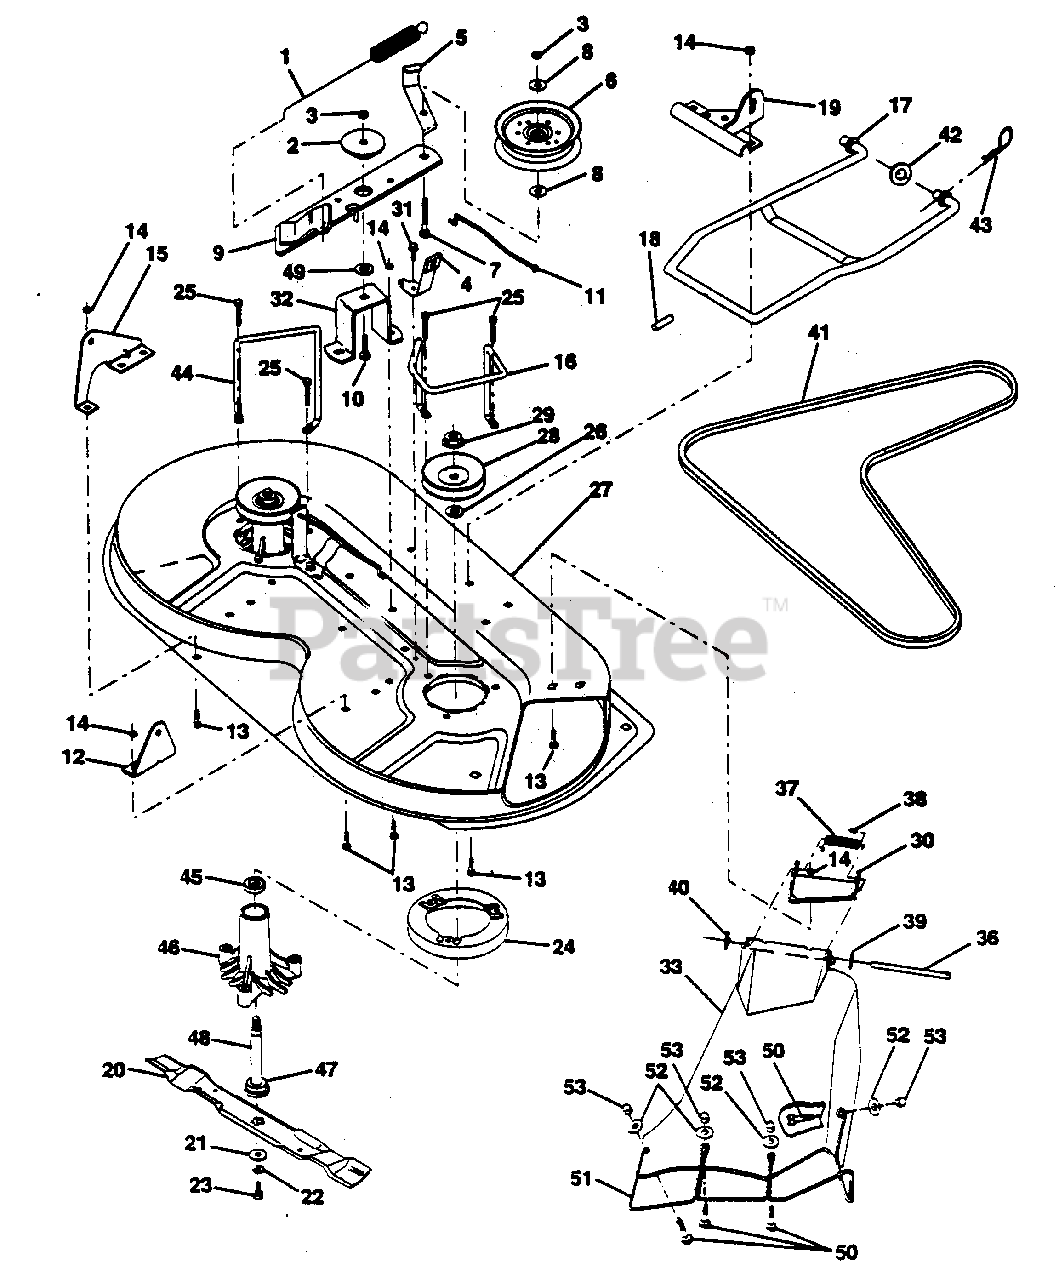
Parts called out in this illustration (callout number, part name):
1	Spring, Mower Clutch
2	Spacer, Retainer
3	Nut, Crownlock 3/8-16
5	Guide, Belt Idler
6	Pulley, Flat Idler
7	Bolt, Carr. 3/8-16 x 1-3/4 Gr. 5
8	Washer 13/21 x 7/8 x 10 Ga.
9	Arm Asm., Idler Mower
10	Bolt, Carriage 3/8-16 x 1-1/4
12	Bracket, Lift R. H. Rear
13	Bolt, Carriage 5/16-18 x 5/8
14	Nut, Crownlock 5/16-18
15	Bracket, Lift L. H. Rear
16	Keeper, R. H.
17	Link, Asm. Mower Stabilizer
19	Bracket, Asm. Front
20	Blade Mulching
22	Washer, Lock 3/8
23	Bolt 3/8-24 x 1-1/4 Gr. 8
24	Stripper
25	Screw Thdrol Hex Hd
26	Washer .150 Thk.
27	Deck Assembly
28	Pulley, Mandrel
29	Nut, Flangelock 9/16
30	Bracket, Asm. Deflector
31	Screw, Hex Wsh. Thdrol. 5/16-18 x 1/2
32	Arm, Support Idler Mower
33	Deflector
36	Rod, Hinge
37	Spring, Torsion Deflector
39	Washer 11/32 x 5/8 x 16 Ga.
42	Washer 11/32 x 5/8 16 Ga.
43	Retainer, Spring
44	Keeper, L. H.
46	Housing Mandrel Vented
47	Bearing
48	Shaft, Mandrel (Includes Key # 47)
49	Washer, Hardened
50	Bolt, RdHd Sqnk M5 x 0.8 x 16
51	Guard, Dftr. Mwr. 36 Tuv
52	Washer 7/32 x 7/16 x 18
53	Nut, Acom M5 x 0.8
